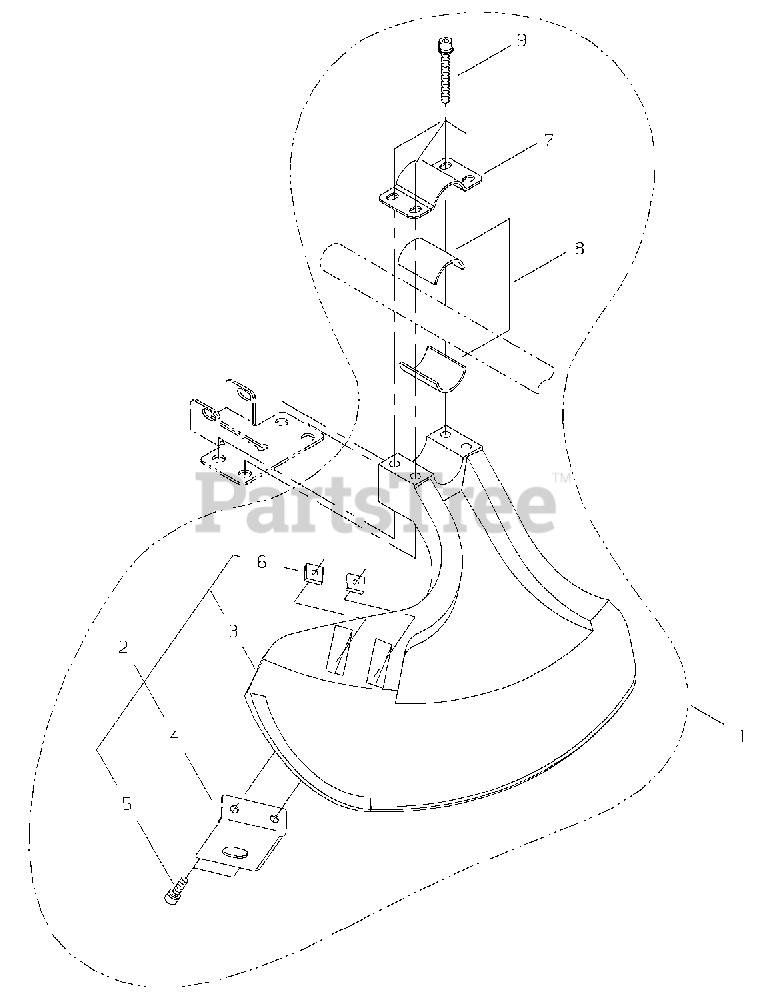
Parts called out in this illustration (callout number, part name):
2	DEBRIS SHIELD ASSY
3	SHIELD
4	BOLT M5×16
5	CUTTER
6	NUT M5
7	CLAMP, UPPER
8	SPACER 26
9	BOLT M5×45
